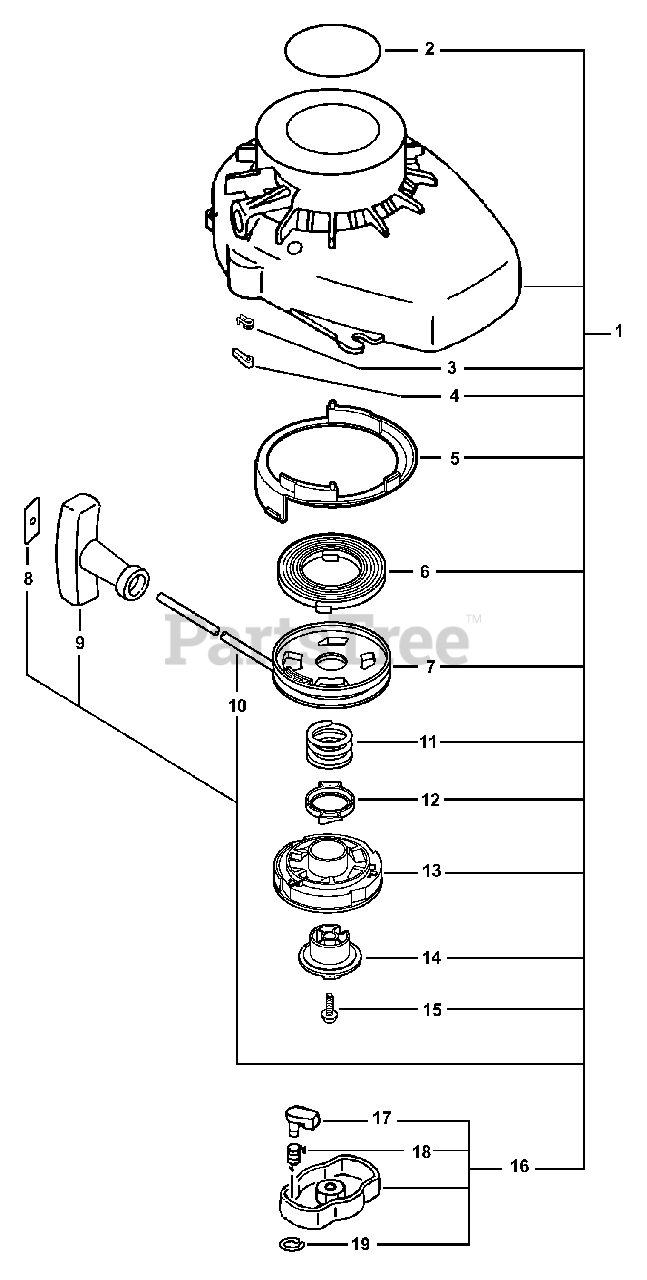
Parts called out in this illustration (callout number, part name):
1	STARTER ASSY
2	LABEL - ECHO -- i
3	SPRING, PAWL RETURN
4	PAWL, STARTER
5	CASE, STARTER
6	SPRING, REWIND
7	REEL, ROPE
8	ROPE, STARTER - 3X800
9	GRIP, STARTER
10	RETAINER, ROPE
11	SPRING, RETURN
13	SPRING ASSY
14	PLATE, CAM
16	STARTER PAWL ASSY
17	PAWL, STARTER
18	SPRING, RETURN
19	RING, RETAINING - 4
